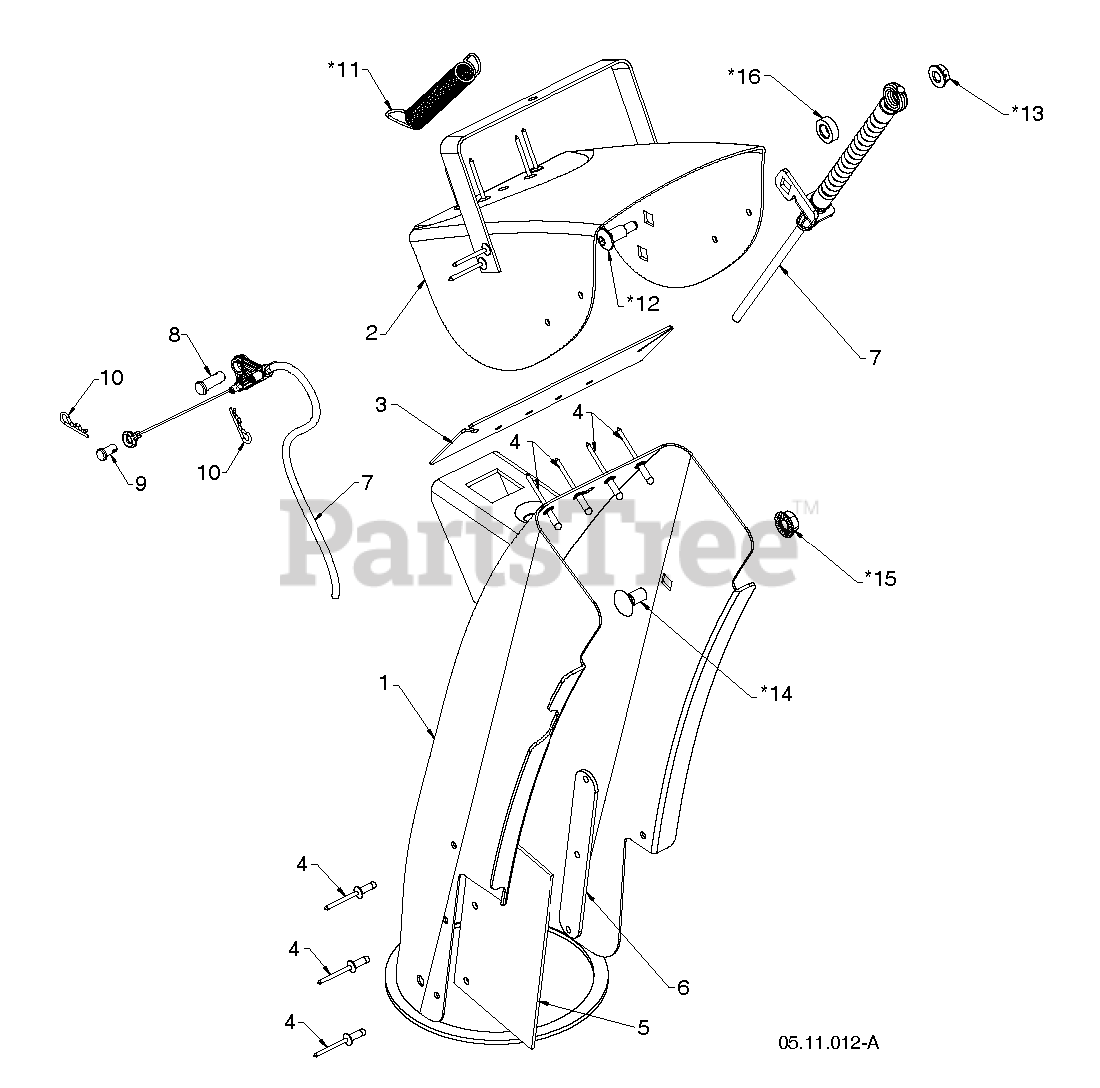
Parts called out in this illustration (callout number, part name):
1	ASM.CHUTE/DEFLECTOR.668
8	PIN CLEVIS 5/16X.875
9	PIN CLEVIS .25 X .31
10	HAIRPIN.SOFT.ZINC.059X1.125
